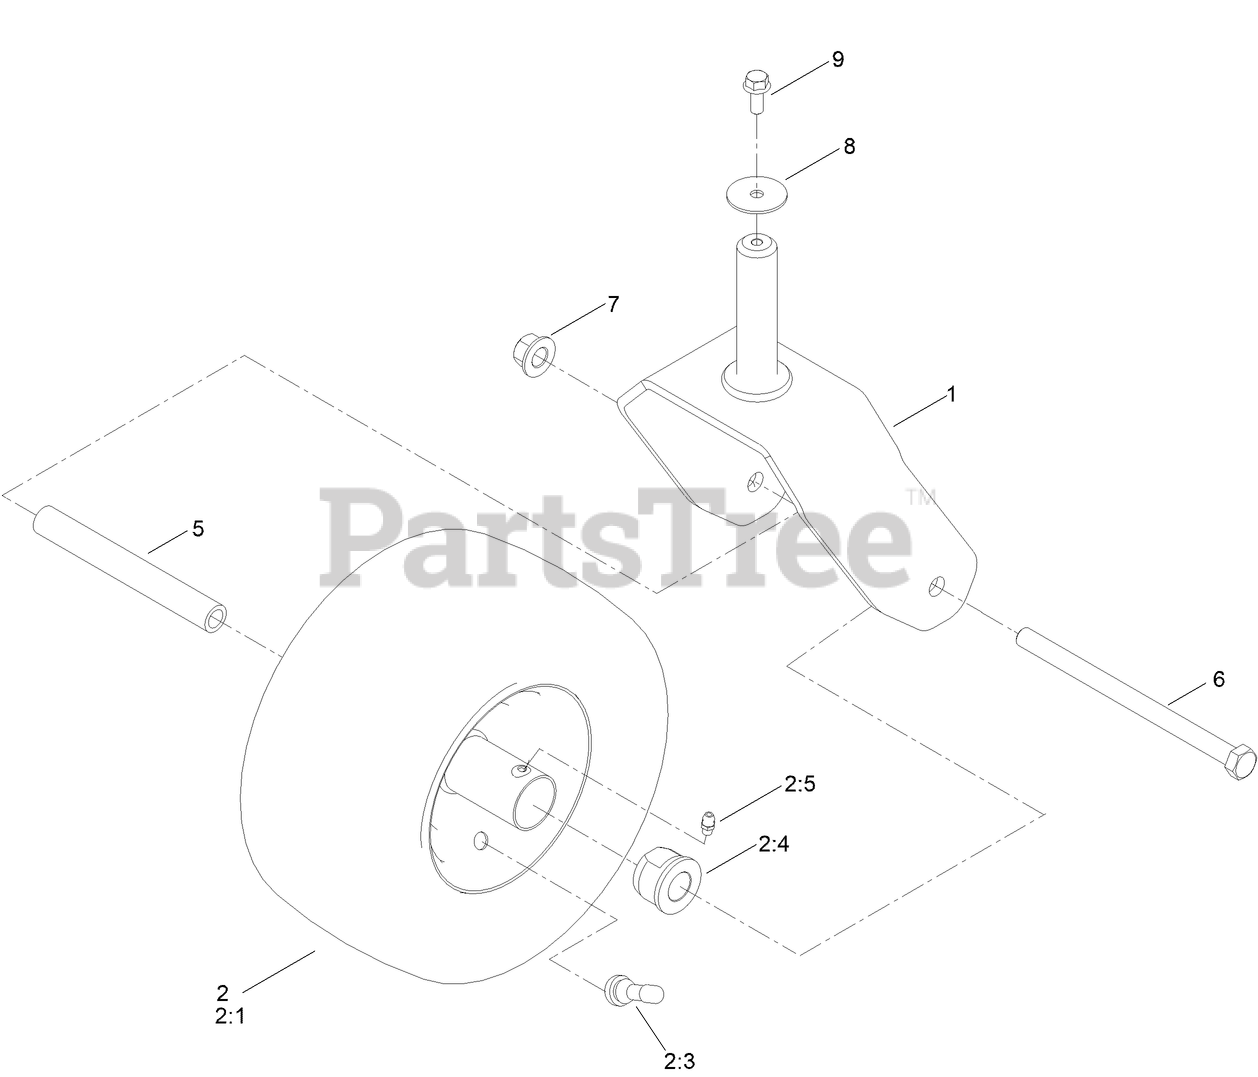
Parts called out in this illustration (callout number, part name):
1	FORK ASM
2	TIRE ASM
2:4	BUSHING-FLANGE
2:5	FITTING-GREASE
5	SPACER-SPANNER
6	SCREW-HH
7	NUT-HF
8	WASHER-FLAT
9	SCREW-HHF
